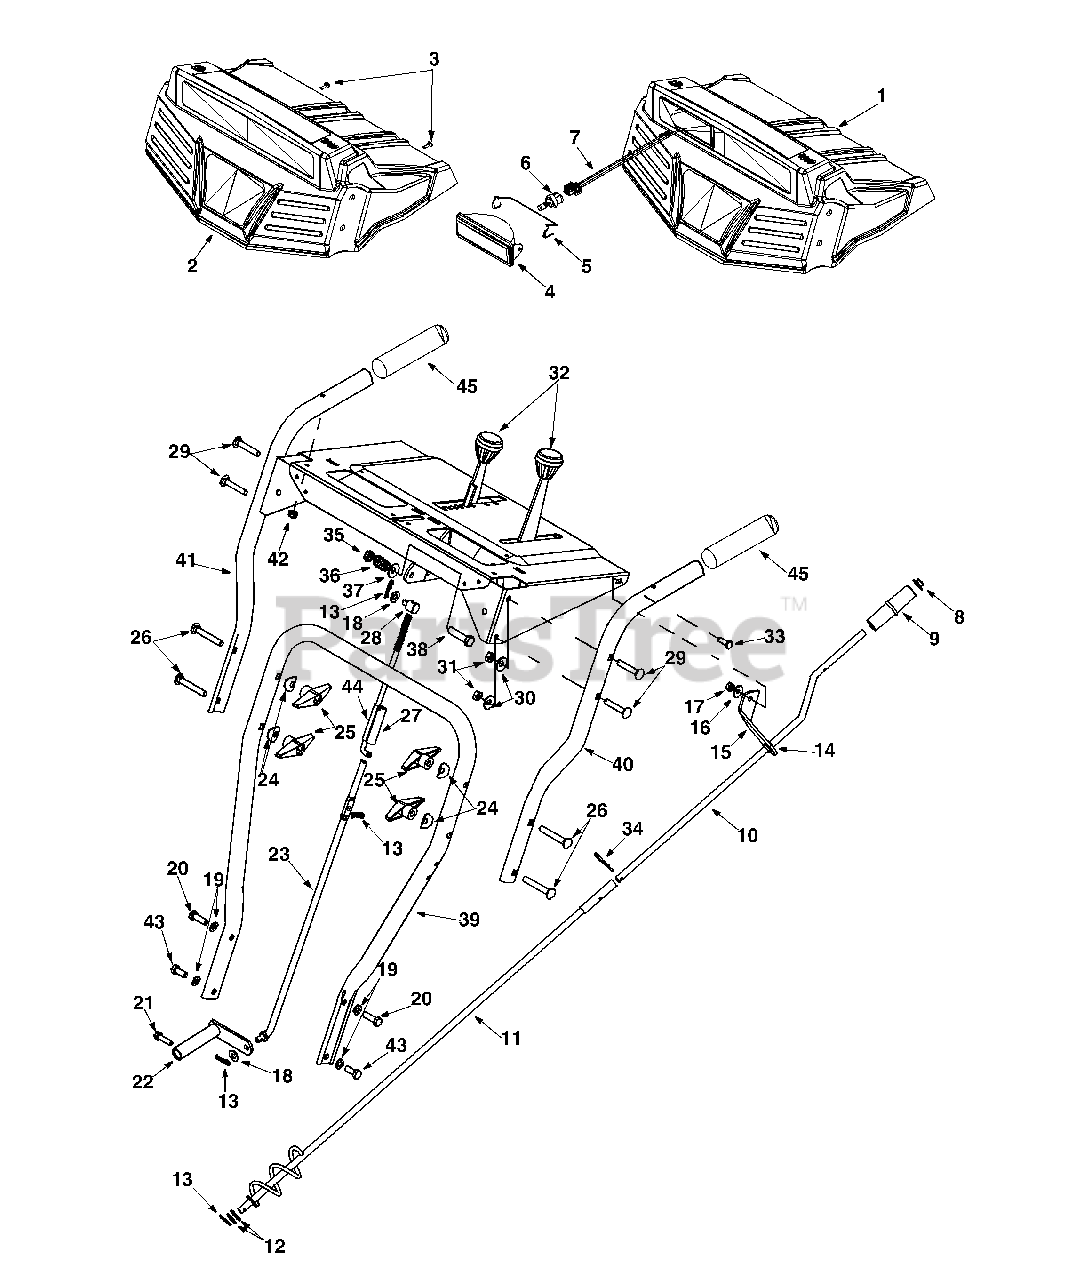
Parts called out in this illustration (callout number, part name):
1	Handle Panel (8526)
2	Handle Panel (7524)
3	Special B Screw
4	Lens Assembly
5	Lamp Retainer
6	Halogen Lamp
7	Lamp Wire Harness
9	Chute Crank Knob
13	Hairpin Clip
14	Plastic Bushing
16	Bell Washer
17	Hex Nut 1/4-20 Thd.
18	Fl-Wash. .344 I.D. x .688 O.D.
19	L-Wash. 5/16
20	Hex Hd. Cap Scr. 5/16-18 Thd.
21	TT-Tap Screw 1/4-20 Thd.
23	Lower Shift Rod
24	Saddle Washer .320 I.D. x .93 O.D.
26	Carriage Screw 5/16-18, Gr. 5
27	Clutch Rod Connector
28	Ferrule
29	Carriage Bolt
30	Bell Washer
31	Hex L-Nut 5/16-18 Thd.
32	Shift Knob
33	Hex Hd. Cap Screw 1/4-20
34	Click Pin
35	Jam L-Nut 3/8-24 Thd.
36	Compression Spring
37	Spring Wash. .401 I.D. x .870 O.D.
38	Hex Hed. Cap Screw 3/8-24 Thd.
43	Hex Patch Screw 5/16-18 Thd.
44	Upper Shift Rod
45	Foam Grip
